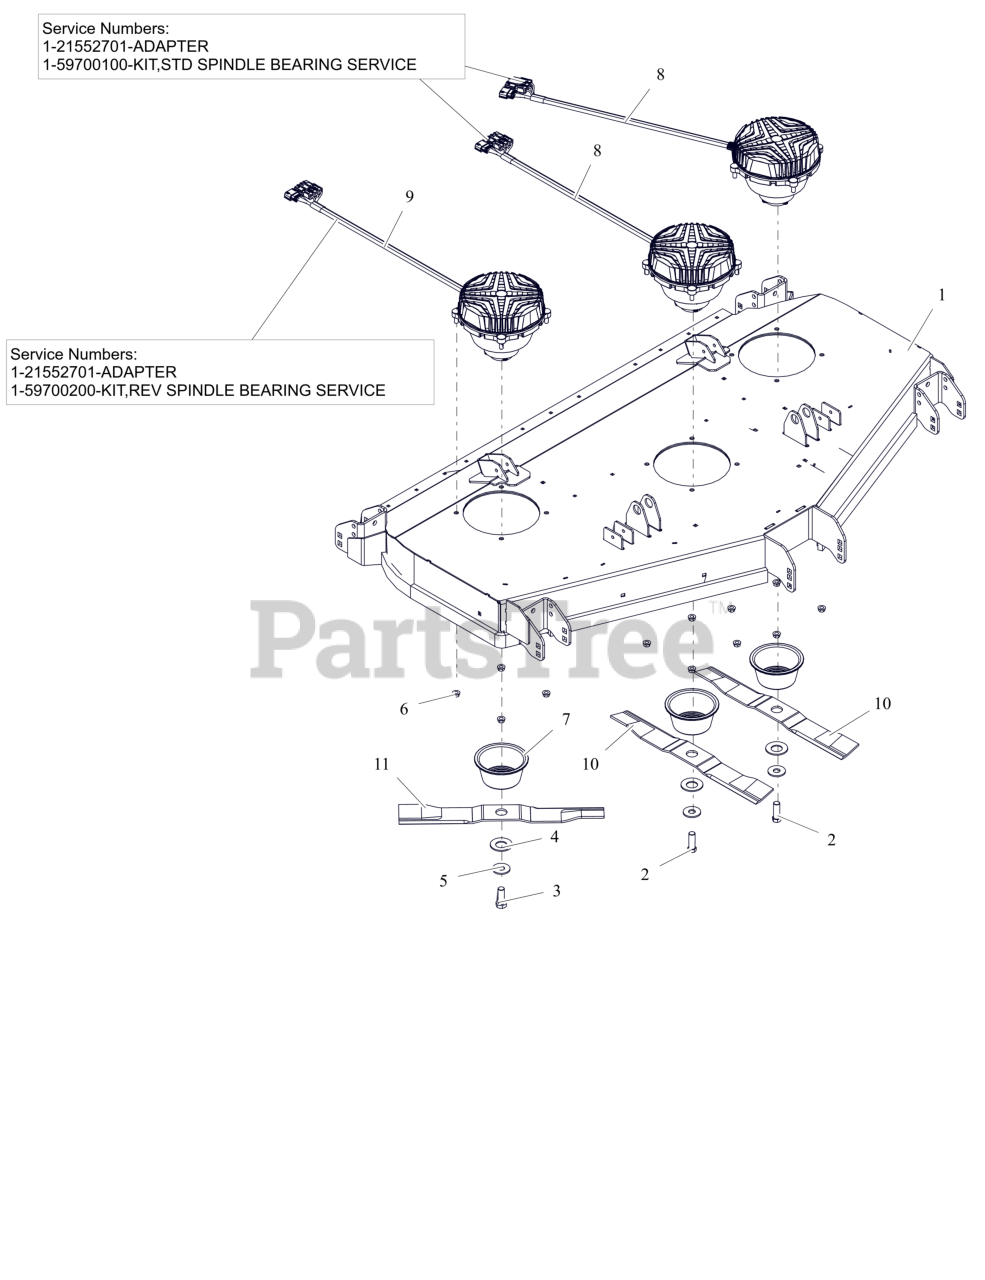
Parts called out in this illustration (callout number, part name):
1	KIT,DECK-60R W/DECALS-ARIENS
2	BLT, HEX .62-18X1.75 G8 ZCC
3	BLT, HEX 0.625-11X1.75 GR8 ZCC LH
4	WSHR, BLVL - .56X28.5X3 PHOS.COAT
5	WSHR, HRDN 0.687X1.75X0.134 HRD
6	NUT-LK-CTR-FLG .375-16 GF ZCC
7	GUARD, SPINDLE LOWER
8	MOTOR, SPINDLE-CW
8	ADAPTER
8	KIT,STD SPINDLE BEARING SERVICE
9	MOTOR, DECK SPINDLE -CCW
9	ADAPTER
9	KIT,REV SPINDLE BEARING SERVICE
10	BLADE, MOWER 20.5"
11	BLADE, MOWER - 20.5" EFF CCW
